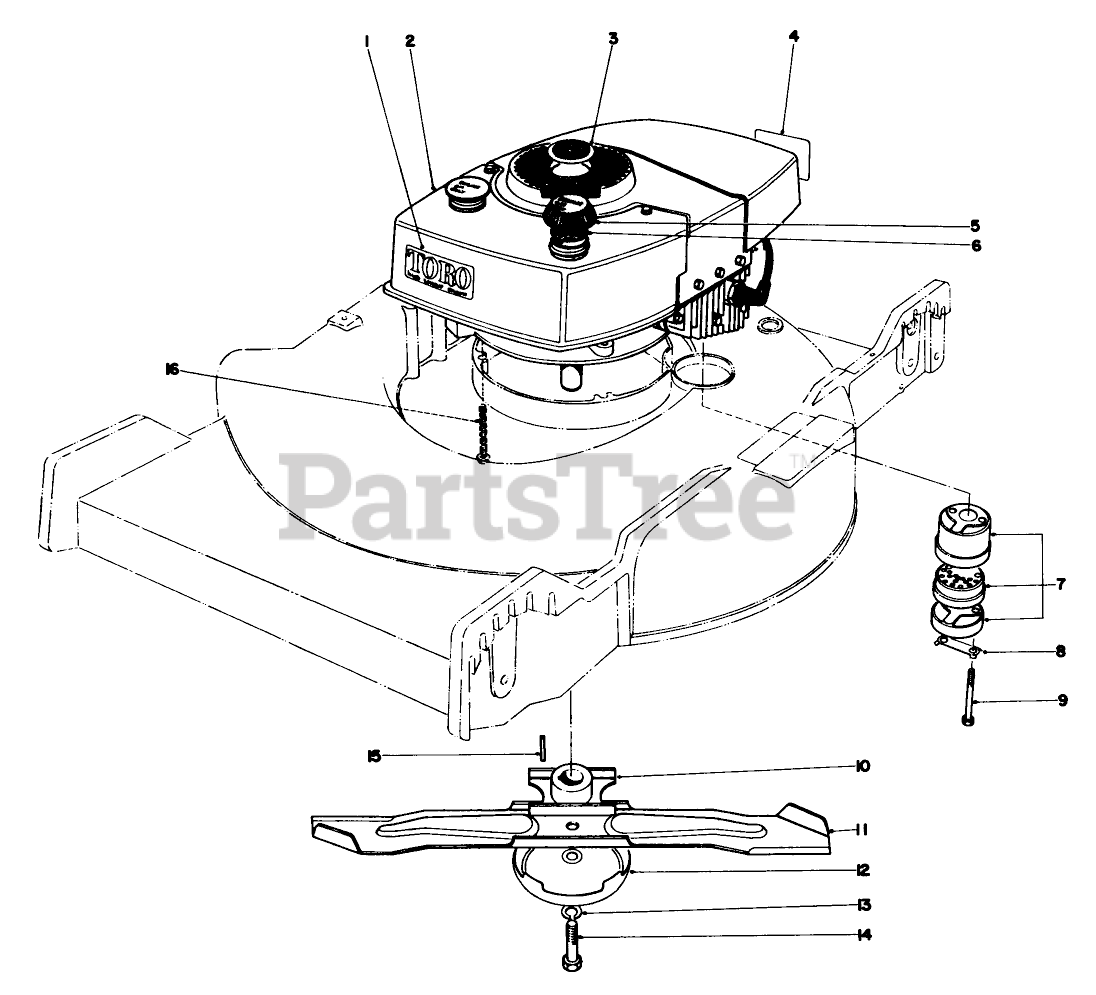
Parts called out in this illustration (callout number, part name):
1	High Torque
2	Engine
3	Plug Button
4	Decal Maintenance
5	Gas Cap (Incl. Ref. #6)
6	Gasket
7	Muffler Assembly
8	CLIP - LOCKING
9	SCREW-HH
10	BLADE RETAINER WA(BLACK)
11	Blade
12	AntiScalp Cup
13	WASHER-LOCK
14	BLADE SCREW
16	3/8-16 X 2-3/4 CAPSCR
